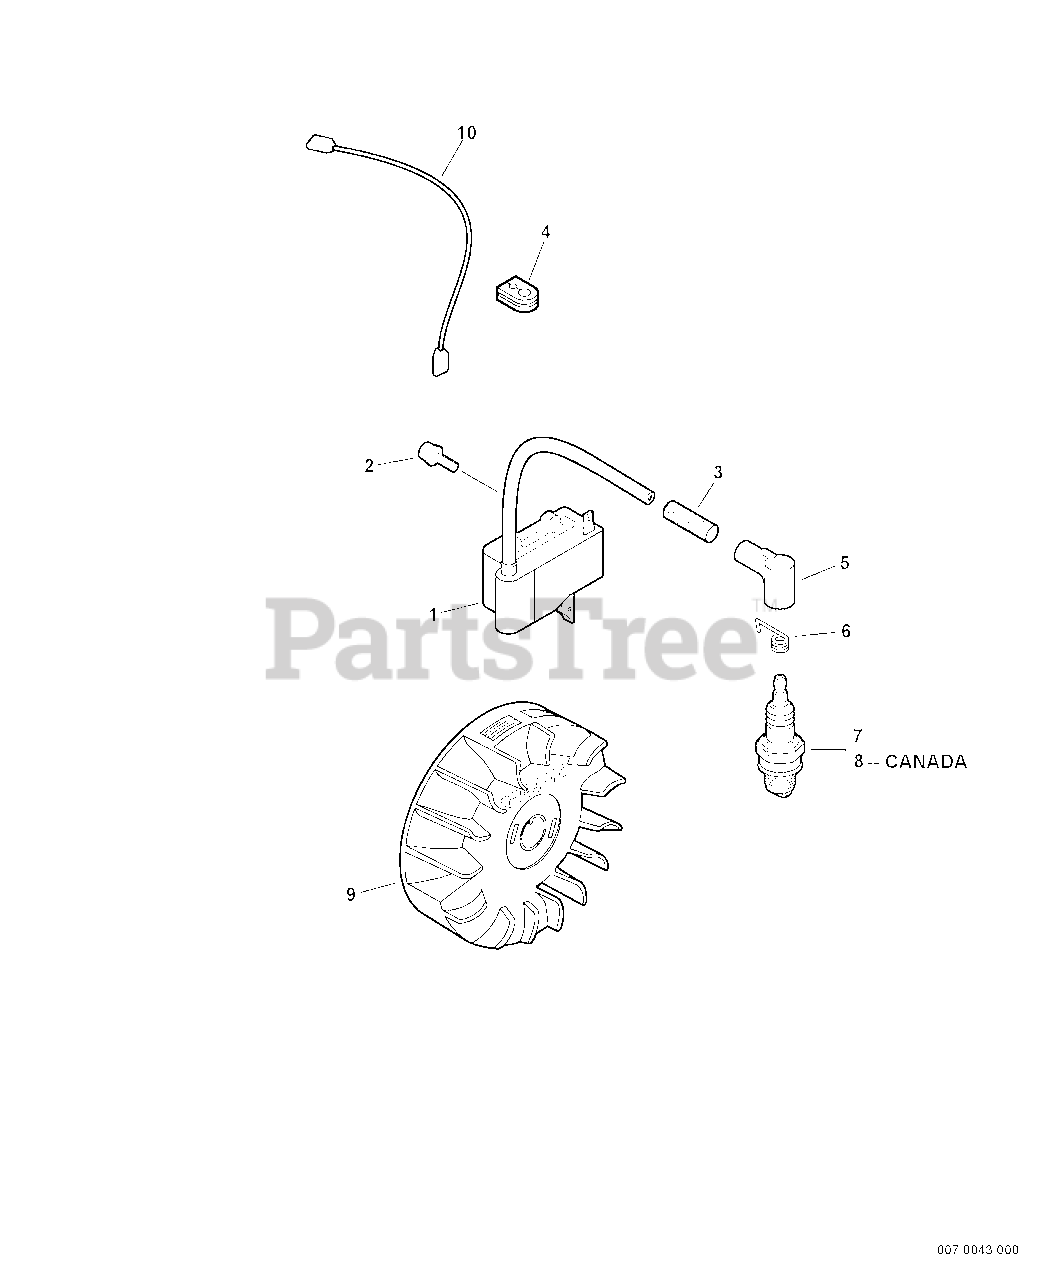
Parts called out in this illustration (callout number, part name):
1	COIL, IGNITION
2	BOLT 4×20
3	TUBE, INSULATOR
5	CAP, SPARK PLUG
6	TERMINAL, SPARK PLUG
7	SPARK PLUG - BPM8Y
8	SPARK PLUG - BPMR8Y
9	FLYWHEEL
